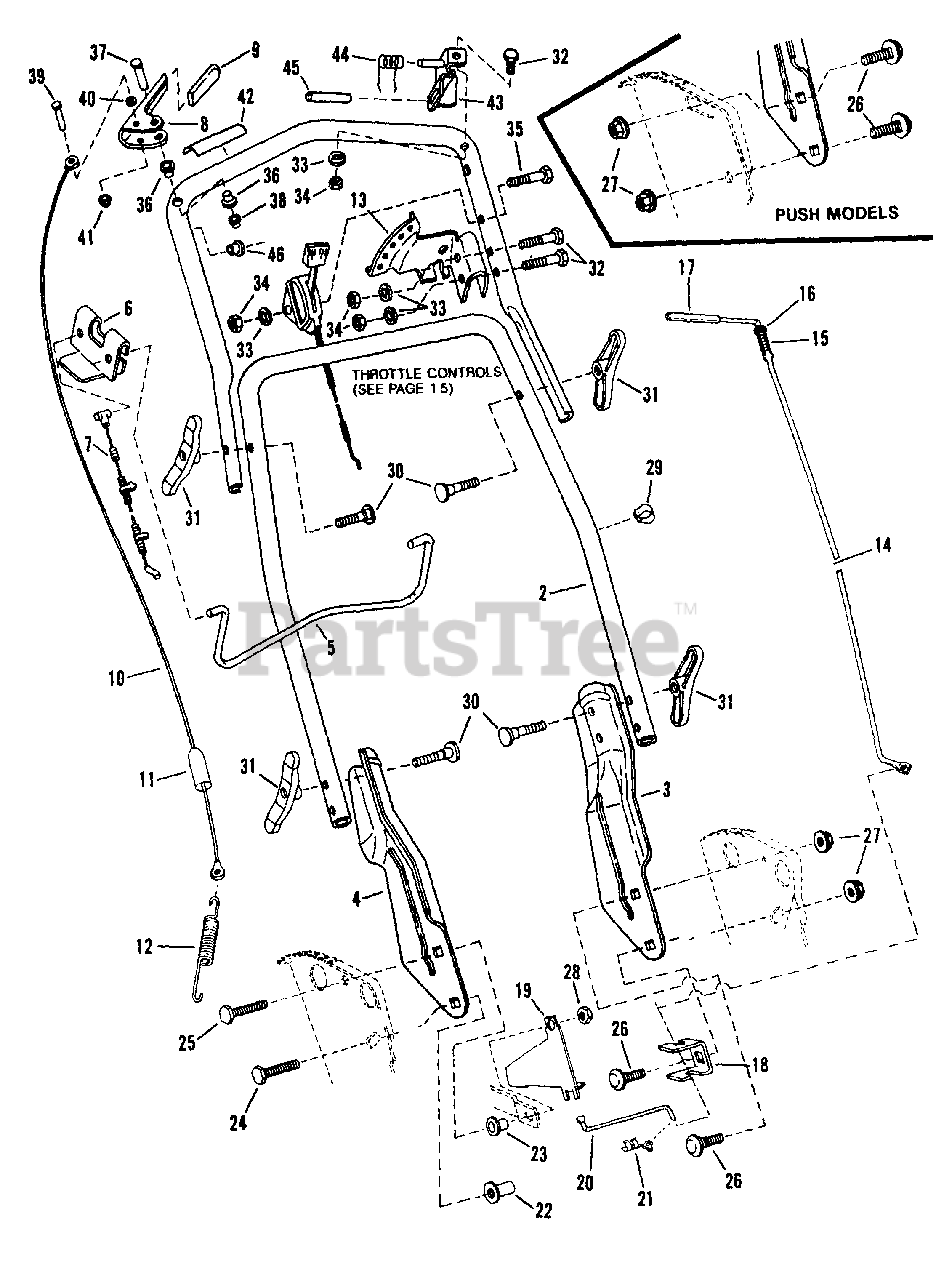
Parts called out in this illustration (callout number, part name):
2	HANDLE, Middle
3	HANDLE, Lower Left Hand
4	HANDLE, Lower Right Hand
5	CONTROL, Blade
6	CLIP, Blade Control
7	CABLE, Blade Control
8	HANDLE, Wheel Drive
9	GRIP, Wheel Drive Handle
10	CABLE, Clutch Pull
11	COVER, Vinyl
12	SPRING, Clutch
13	SECTOR, Speed
14	LEVER, Speed Control (Replaces 1-2110)
15	SPRING, Speed Control
16	WASHER, 3/8" Flat
17	GRIP, Speed Control Handle
18	ANCHOR, Speed Control
19	GUIDE, Lower V-Belt
20	ROD, Transfer
21	CLIP, Transfer Rod
22	TEE-NUT, 5/16-18
23	BUSHING, Differential
24	BOLT, 5/16-18 x 3/4 Flange Lock
25	CAPSCREW, 5/16-24 x 1
26	BOLT, 5/16-18 x 5/8 Carriage
27	NUT, 5/16-18 Hex Flange Lock
28	NUT, 5/16-24 Center Lock
29	CLIP Cable/Wiring
30	SCREW, 1/4C x 1-7/8 Curved Head
31	WING-NUT, 1/4C
32	CAPSCREW, 1/4-28 x 1-3/8
33	LOCKWASHER, 1/4 Internal Tooth
34	NUT, 1/4-20 Hex
35	CAPSCREW, 1/4-28 x 1-3/4
36	BUSHING
37	PIN, Clutch Handle
38	PUSH-NUT (for handle pin)
39	PIN, 1-3/4 LG (Clutch cable)
40	WASHER, 010 Flat
41	PUSH-NUT (for clutch pin)
42	DECAL, Blade Control
43	ASSEMBLY, Blade Control Bracket
44	SPRING, Blade Control
45	GRIP, Pivot
46	BUSHING
